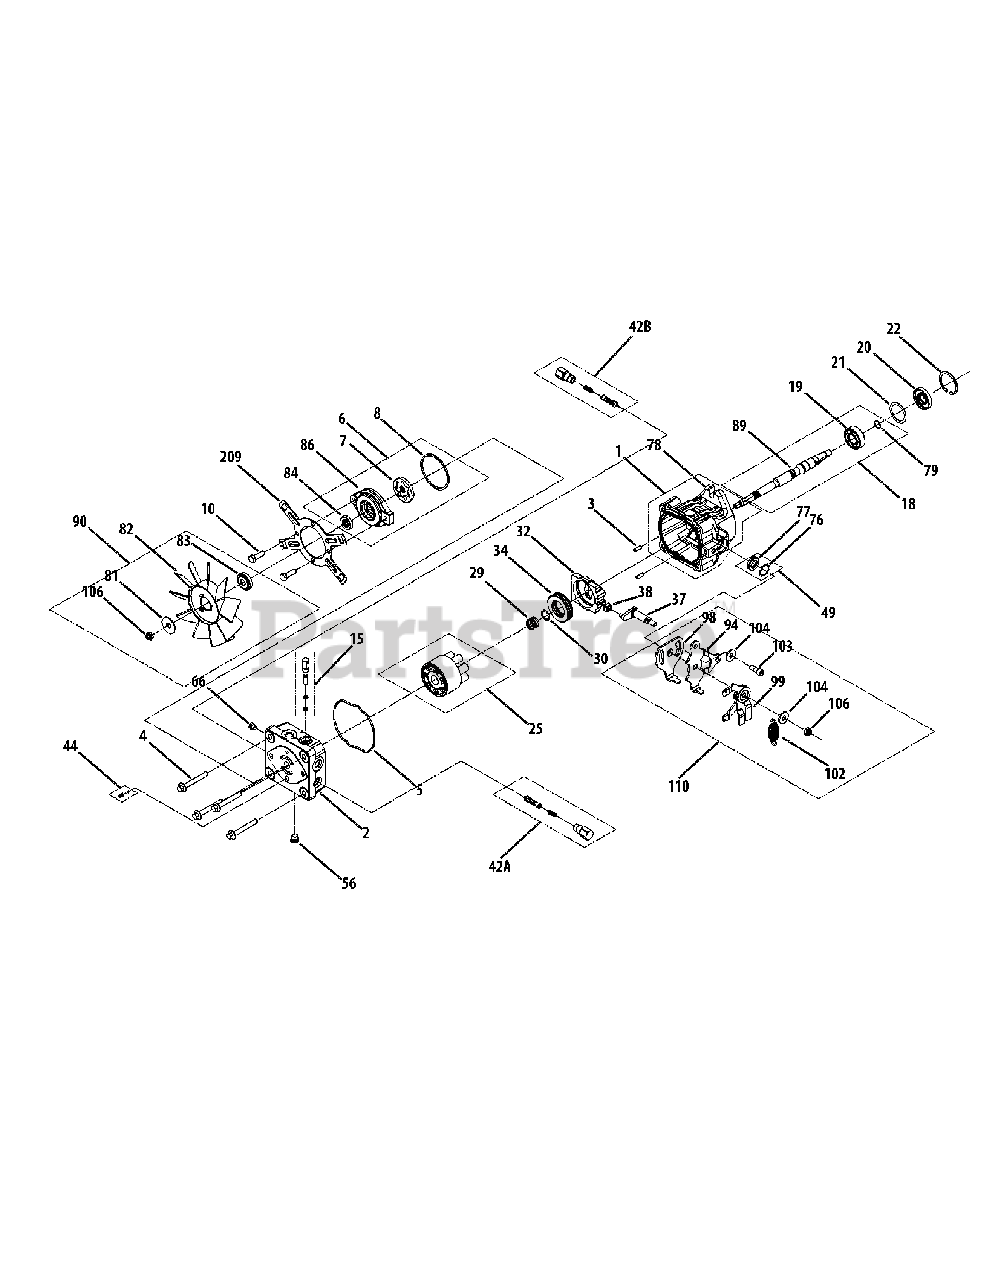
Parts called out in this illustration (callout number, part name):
1	Kit, Housing
1	Housing, Pump
2	Kit, Endcap
2	Plug 9/16-18 (Metal)
3	Straight Headless Pin
4	Hex Bolt M8-1.25 x 60mm Long
5	Housing, O-Ring
6	Kit, Charge Pump
6	Gerotor
6	O-Ring
6	Housing, Charge Pump
10	Screw, 5/16-18 x 1.00 Long
15	Kit, Bypass Valve
18	Kit, Pump Shaft
18	Bearing, Ball 17 x 40 x 12
18	Ring, Ret. Wire .561 I.D.
18	Shaft, Input Tapered Keyed
20	Lip Seal 17 x 40 x 7 PTC
22	Retaining Ring
25	Cylinder Block Kit
29	Block Spring
30	Block Thrust Washer
34	Ball Thrust Bearing
37	Arm, Trunnion Tapered Square
42A	Kit, Shock Valve
42B	Kit, Shock Valve
44	Charge Relief Kit
49	Trunnion Seal / Retainer Kit
49	Ring, Ret. -Star Wash 1.0
49	Seal, Lip 12 x 25 x 5
56	Plug - 7/16-18 Steel (Diagnostic)
90	Washer, .40 x 1.55 x .06
90	Fan, 6", 10 Blade
90	Fan Hub
90	Nut, Lock, Side 5/16-24UNF-2B
100	Overhaul Seal Kit
100	O-Ring, Housing
100	O-Ring
100	Seal, Lip 17 x 40 x 7
100	Ring, Retaining
100	Seal, Lip 12 x 25 x 5
110	Arm, Control
110	Arm, RTN
110	Assembly, RTN Bi-Directional
110	Spring, Extension (STD)
110	Screw, 5/16-24 x .75 (Patch)
110	Washer
110	Nut, Lock, Side 5/16-24UNF-2B
209	Bracket, Shroud
